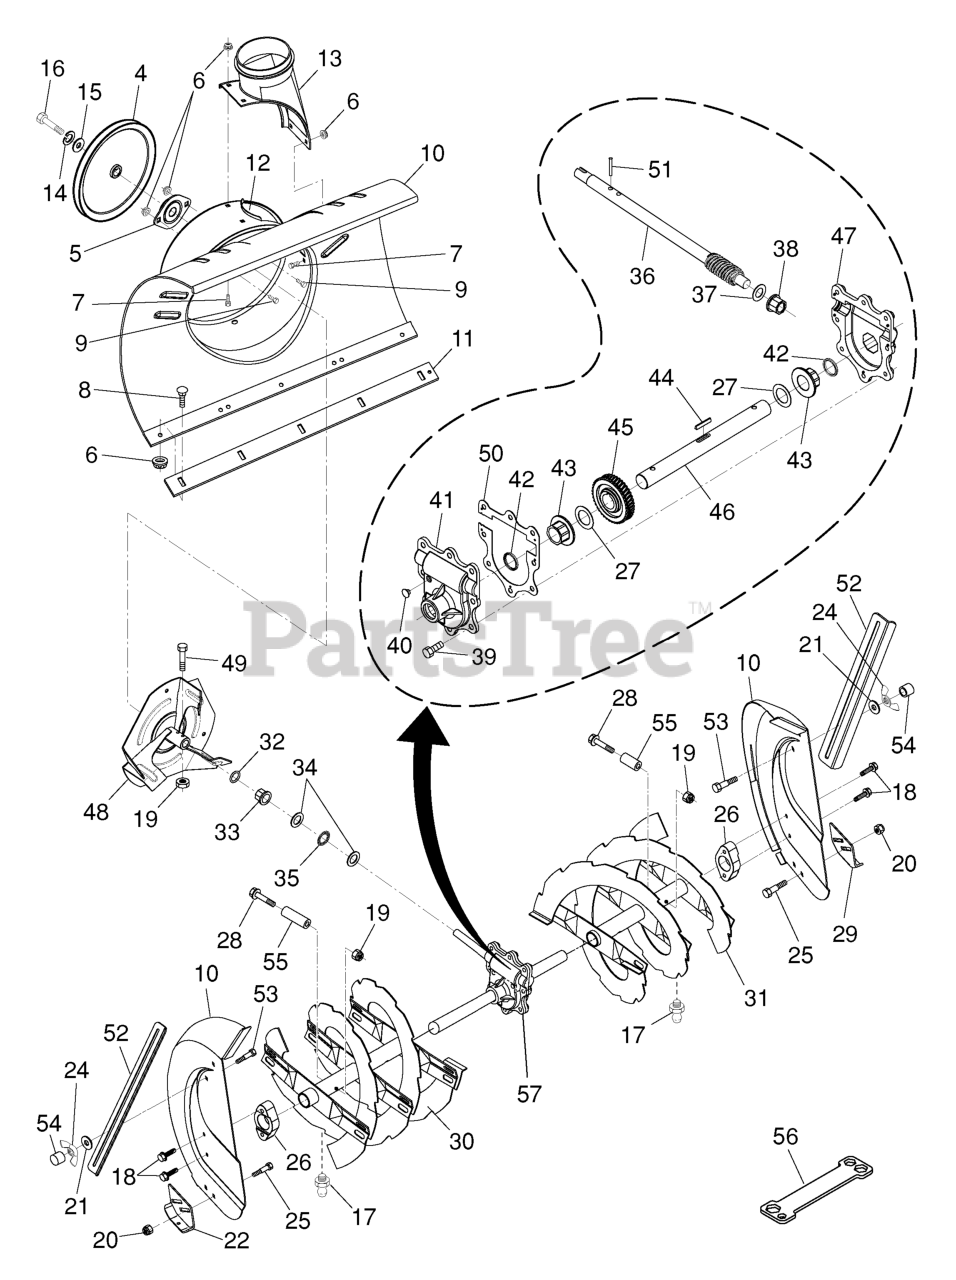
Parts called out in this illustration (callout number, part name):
4	PULLEY, IMPELLER
5	BEARING FLANGE
6	NUT, HEX FLANGE 5/16-18
7	BOLT.CARRIAGE.5/16-18X
8	BOLT
10	HOUSING, AUGER
11	IPL MISTAKE
12	BRACKET, CORNER DISCHARGE
13	BASE DISCHARGE CHUTE
14	WASHER, FLAT
15	WASHER, LOCK 5/16
16	Screw, Hex Head 5/16-18 x 3/4
17	GREASE FITTING
18	SCREW, HEX HD 5/16X1
19	LOCKNUT.NYLOC.1/4-20
20	NUT, HEX FLANGE 5/16-18
21	WASHER.12021.438X.75X.06.PLS
22	WASHER.12021.438X.75X.06.PLS
24	NUT WING PM
25	BOLT
26	BEARING, AUGER
27	WASHER TRUST 1"
28	BOLT, SHEAR
29	SKID PLATE
30	AUGER ASSEMBLY, RH
31	AUGER ASSEMBLY, LH
33	BUSHING, FLANGE 3/4
34	WASHER, THRUST 3/4
35	BEARING TRUST 3/4 NTA-1220
36	SHAFT, IMPELLER
37	WASHER, THRUST 5/8
38	FLANGE BUSHING-5/8
39	HEX SCREW-5/16 X 3/4
40	CASE PLUG
41	GEARBOX HOUSING-RH
42	OIL SEAL
43	FLANGE BUSHING-1"
44	KEY, SQUARE 1/4 X .875
45	WORM GEAR
46	AUGER SHAFT
47	HOUSING.GEARBOX.LH(SERVICE)
48	IMPELLER ASSY
49	SCREW.HEX.HD1/4-20X
50	GEARBOX GASKET
51	PIN, ROLL 3/16 X 1-1/8
52	BAR, DRIFT
53	BOLT, HEX HEAD
54	STOP.11261.PLASTIC.30X50L.RED
55	SPACER.3943.SLEEVE.250X.47
56	RP WRENCH, SNOWTHROWER
57	GEARBOX.ASSEMBLY.AUGER
